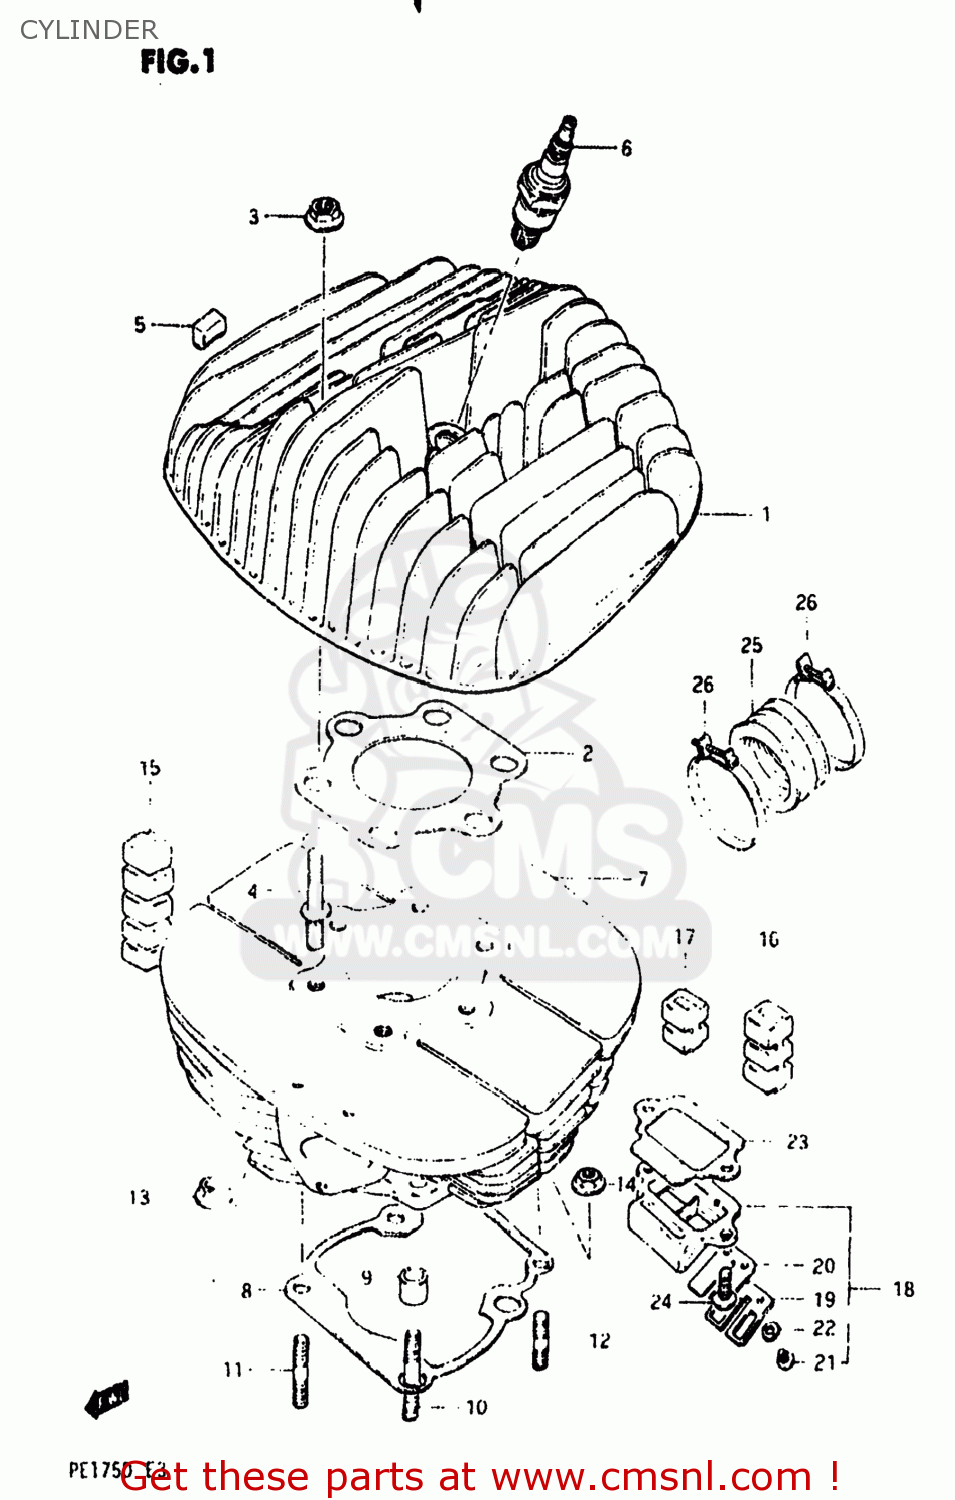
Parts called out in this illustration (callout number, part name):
1	HEAD,CYLINDER
2	GASKET,CYLINDER HEAD (NAS)
3	NUT
4	BOLT,STUD
5	PAD,CYLINDER
6	PLUG,SPARK(B10EGV)
7	CYLINDER
8	GASKET,CYLINDER (MCA)
9	PIN
10	STUD 8X40
11	STUD 8X25
12	STUD 6X25
13	NUT
14	NUT
15	PAD,CYLINDER
16	PAD,CYLINDER
17	PAD,CYLINDER
18	VALVE ASSY,REED
19	STOPPER,REED VALVE
20	VALVE,REED
21	SCREW
22	LOCK WASHER
23	GASKET,REED VALVE (MCA)
24	SCREW
25	PIPE,INTAKE
26	CLAMP
